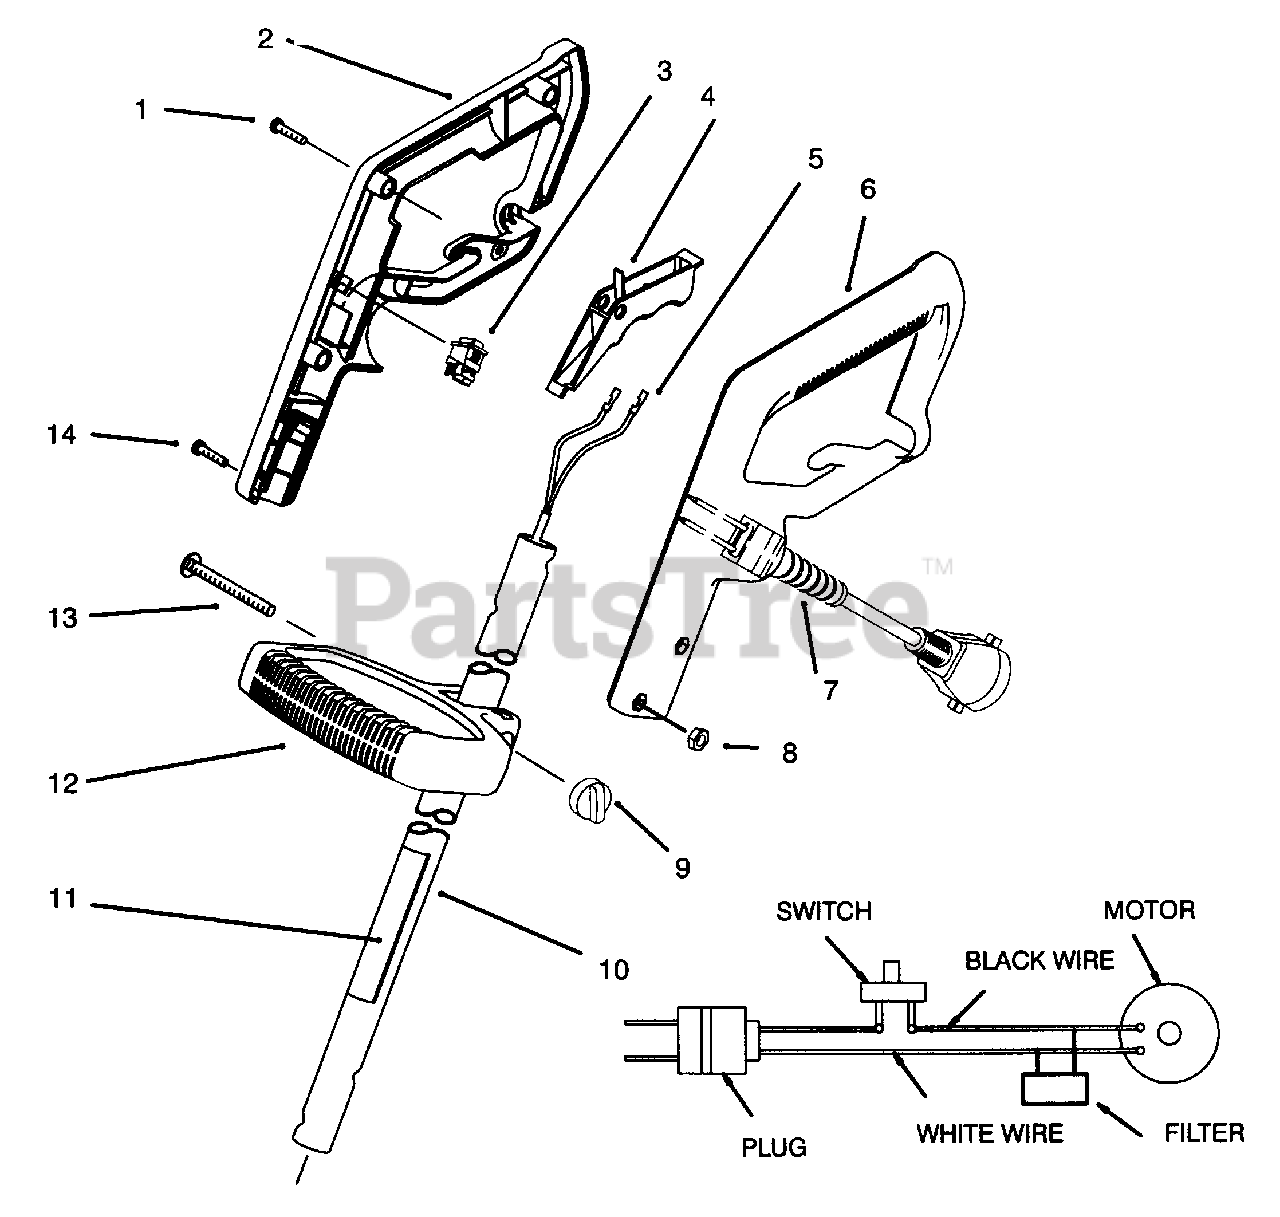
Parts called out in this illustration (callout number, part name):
1	Screw-Pan Hd Tapping
2	Grip-Hand R.H.
5	Harness-Wire
6	Grip-Hand L.H.
7	Cord-Power
8	Nut-Lock
10	Tube Assembly (Incl. Ref. #11)
11	Decal-Safety
12	Handle-Mid
13	Screw-Carriage
14	Screw-Pan Hd.
